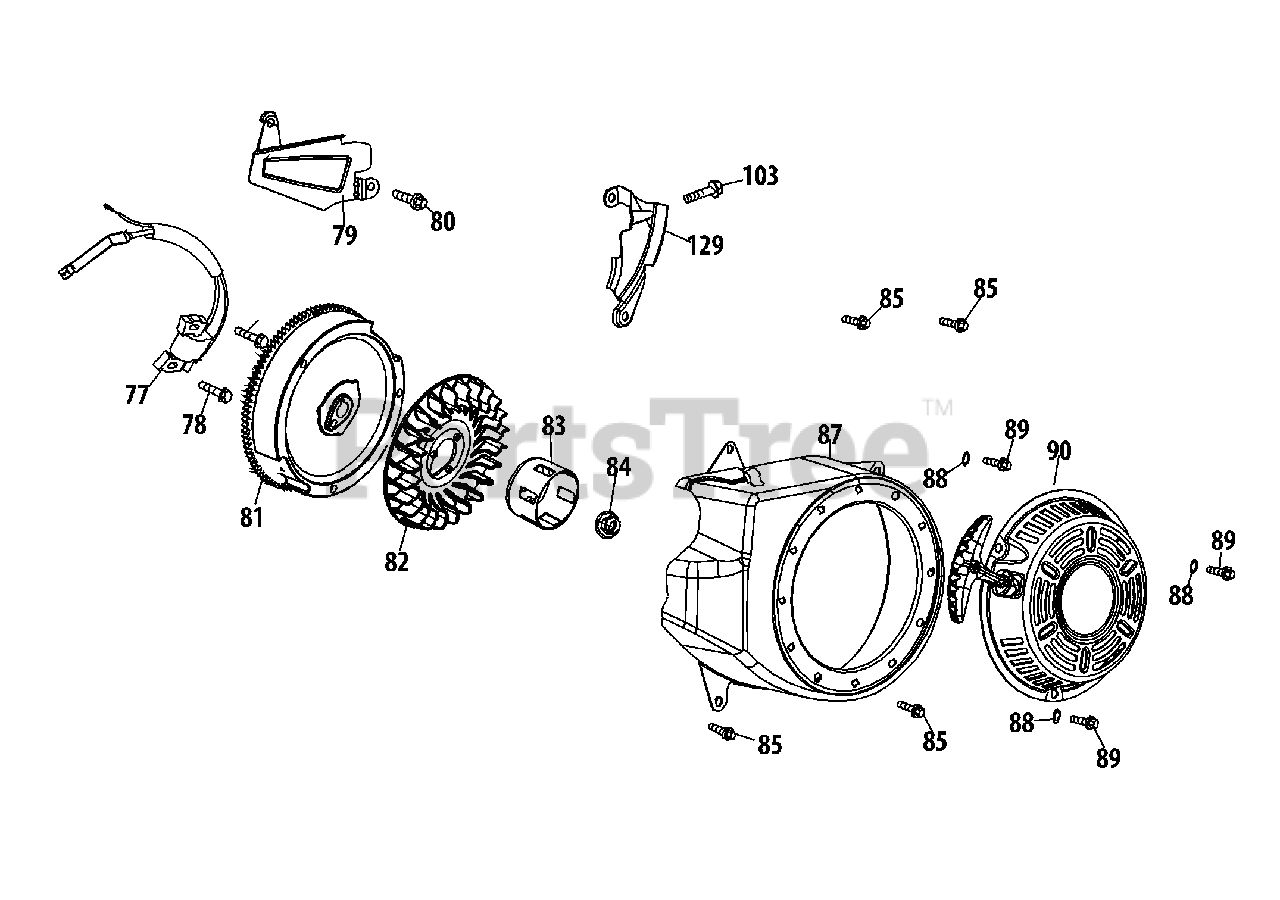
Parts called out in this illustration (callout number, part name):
77	Ignition Coil Assembly
78	Bolt M6×25
79	Air Flow Shield
80	Bolt M6×10
81	Flywheel
82	Cooling Fan
83	Pulley,Starter
84	Flywheel Nut,M14×1.5
85	Bolt M6×12
87	Blower Housing
88	Washer
89	Bolt M6×10
90	Recoil Starter Assembly
103	Bolt M6×12
129	Blower Housing Shield
